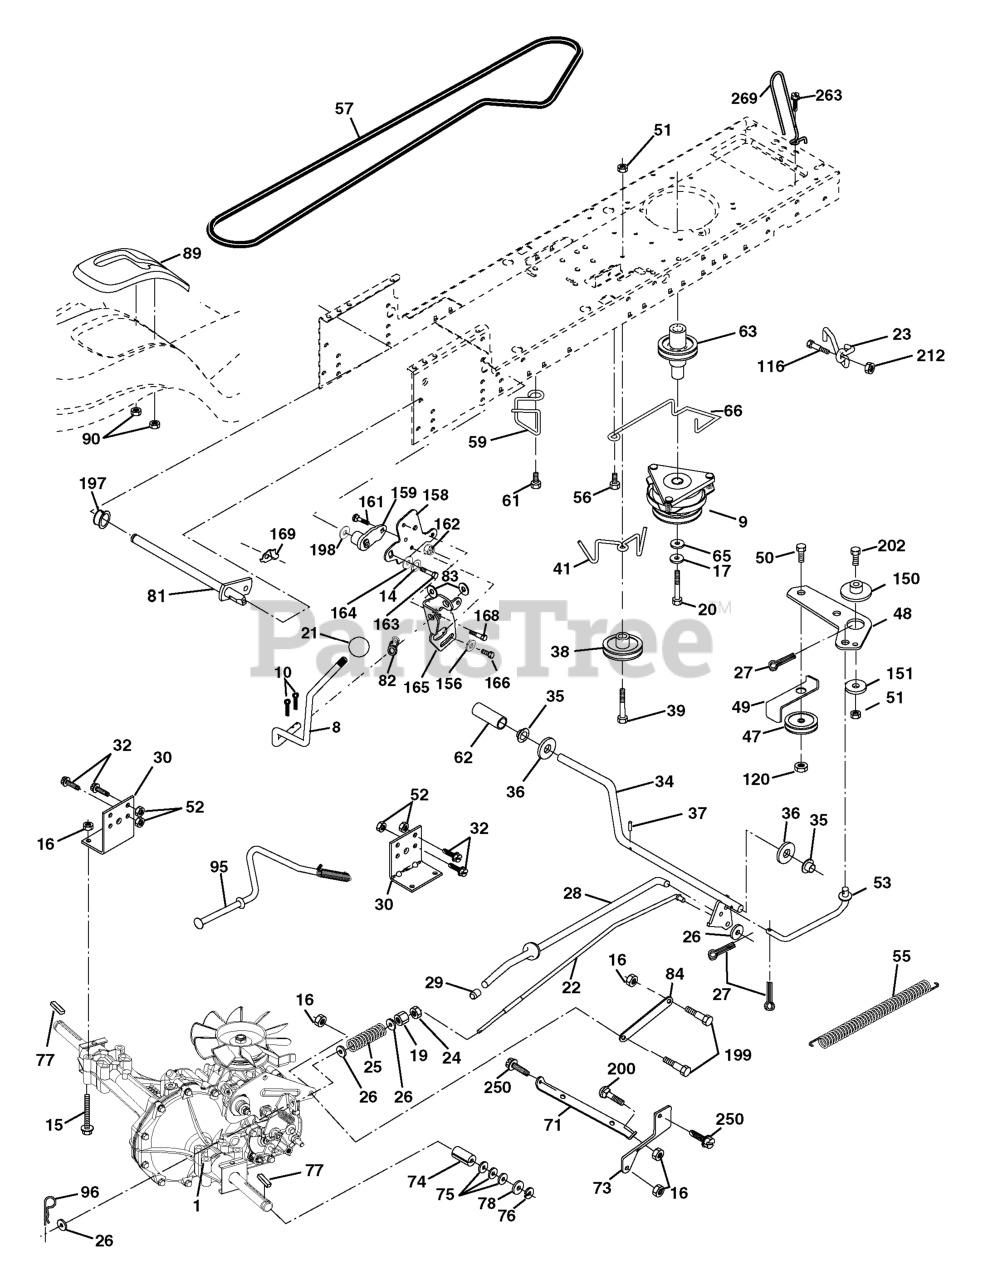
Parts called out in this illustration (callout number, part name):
8	ROD SHIFT FENDER ADJUST STLT
9	CLUTCH ELECTRIC
10	PIN COTTER
14	LOCKWASHER
15	BOLT HEX 5/16-18 GR 5
16	NUT.71038.31-18.HEX.NYLOCK
19	NUT
20	BOLT HEX 7/16-20X4-1/4"
21	KNOB.DELUXE.(PISTOL.GRIP).BLAC
22	ROD BRAKE HYDRO
23	BRKT ASM MTNG
24	NUT
25	SPRING ROD LT
26	WASHER
27	COTTER PIN
28	ROD, PARKING BRAKE
29	PLUNGER CAP
30	BRKT, TRNSXLE MNT 20"
32	BOLT
34	SHAFT, FOOT PEDAL
35	BEARING.NYLON
36	WASHER LT
37	DRIVE PIN
38	PULLEY IDLER COMPOSITE
39	BOLT
41	KEEPER, BELT IDLER
47	IDLER PULLEY
48	BELLCRANK, CLUTCH
49	RETAIN BELT
50	BOLT.3/8-16X1.50
52	LOCKNUT
53	LINK, CLUTCH LT
55	SPRING, RETURN LT
56	SCREW.3/8-16
57	DRIVE BELT, LTH & YTH TRACTORS
59	KEEPER, BELT CENTER
61	SCREW 3/8-16X.875
62	PEDAL COVER T
63	PULLEY- ENGINE
65	LOCKWASHER
66	KEEPER BELT ENGINE
71	STRAP TORQUE LH HYDRO
73	STRAP TORQUE RH HYDRO
74	SPACER AXLE
77	SQUARE KEY
81	SHAFT ASM CROSS TAPERED
82	SHIFT SPRING
83	WASHER
84	LINK TRANSAXLE
89	SHIFT CONSOLE
90	NUT.PUSH.3/16
95	CONTROL ASM. BYPASS HYDRO
96	RETAINER M
116	BOLT D
120	NUT LOCK FLG 3/8-16 UNC
150	SPACER, RETAINER
151	WASHER 12/32X2X10GA
156	WASHER.SRRTD.5/16
158	BRACKET
159	HUB
161	BOLT
162	NUT.CROWNLOCK.1/4
163	BOLT
164	Washer 5/8 x .281 x 10 Ga
165	RP BRACKET
168	BOLT.SHOULDER.5/16-18X
169	PLATE.FASTENING.CROSS.SHAFT
197	NYLINER SNAP 5/8" ID
198	WASHER.NYL.7/8IDX.105"HYD CR
199	BOLT SHOULDER 5/16-18 UNC
200	BOLT
212	NUT
250	SCREW 3/8-16X3/4
